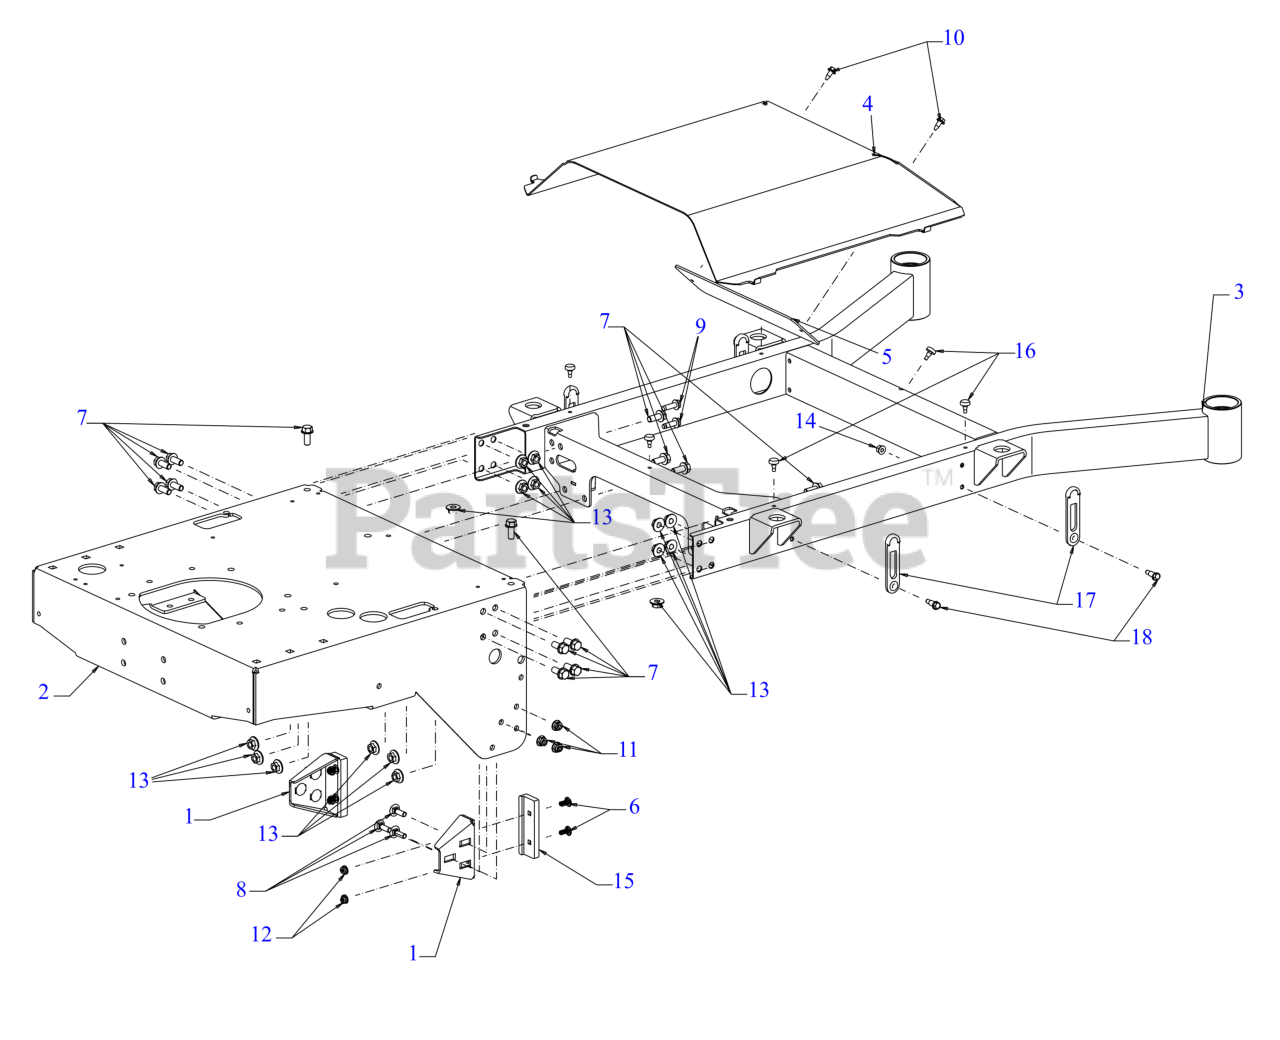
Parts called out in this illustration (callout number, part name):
1	DECK BUMPER BRACKET (LH)
2	ENGINE/TRANS FRAME
3	FRAME (FRONT)
4	DECK COVER
5	BACK PLATE
6	CARRIAGE BOLT 1/4-20 x .62
7	SCREW 3/8-16 x .875 GR5
8	SCREW 5/16-18 x 1.00 GR5
9	SCREW 5/16-18 x 1.00
10	SCREW 1/4-20X.625
11	FLANGE LOCK NUT 5/16-18
12	FLANGE LOCK NUT
13	FLANGE LOCK NUT
14	LOCK NUT 1/4
15	BUMPER PAD
16	RUBBER BUMPER
17	COVER STRAP 2.50 LONG
18	SHOULDER SCREW
